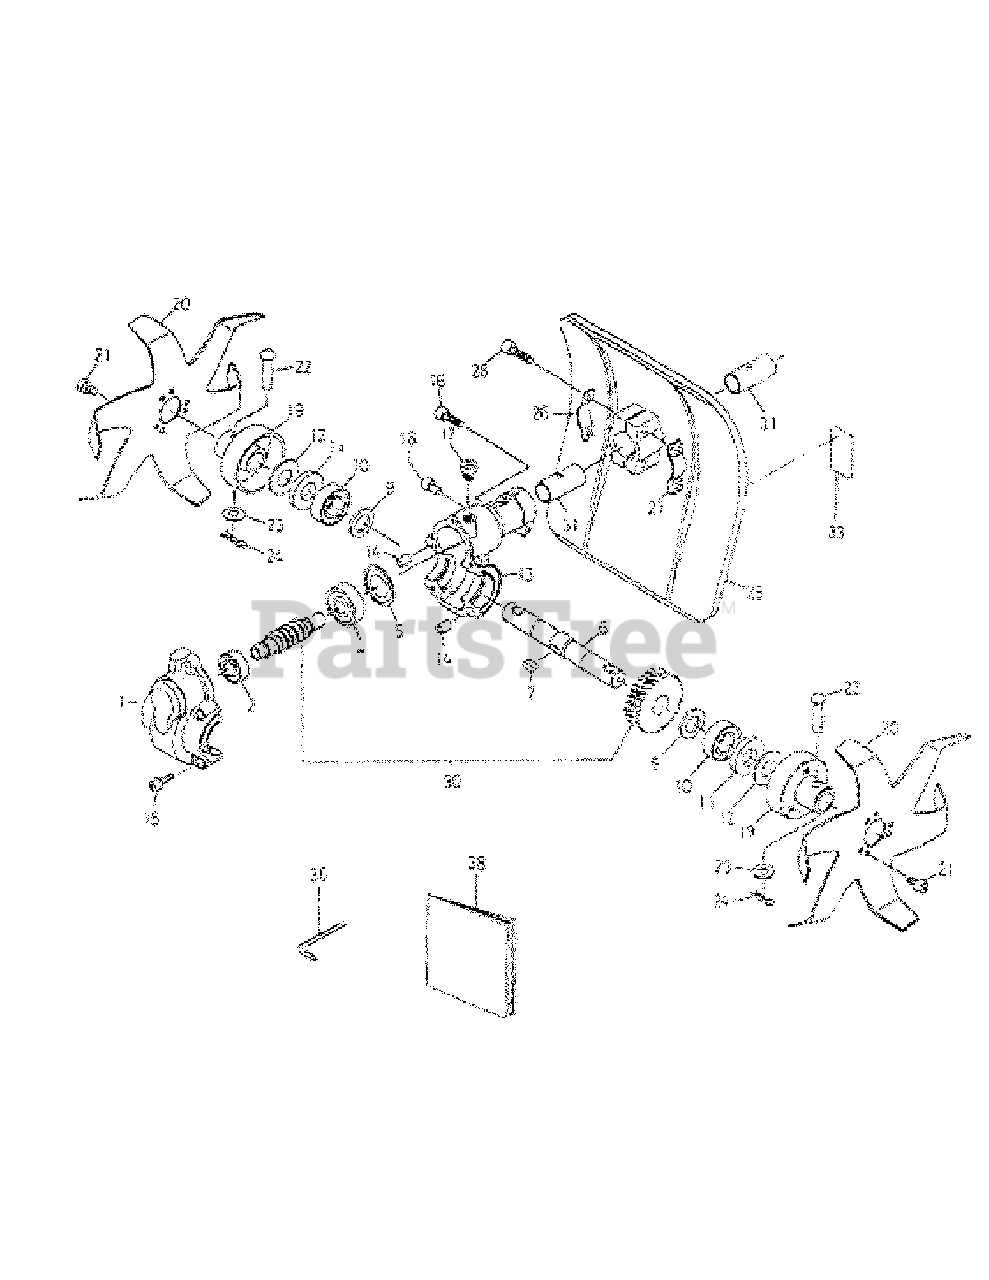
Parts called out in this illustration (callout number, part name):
2	Ball Bearing 6001zz
4	Ball Bearing 6301zz
10	Ball Bearing 6003zz
15	Bolt, M5X25mm
16	Bolt, M6X18mm
18	Bolt M5X10mm
19	Holder, Rotor
30	Gear Assembly
33	Caution Plate
36	Wrench, Torx
38	Instruction Book
